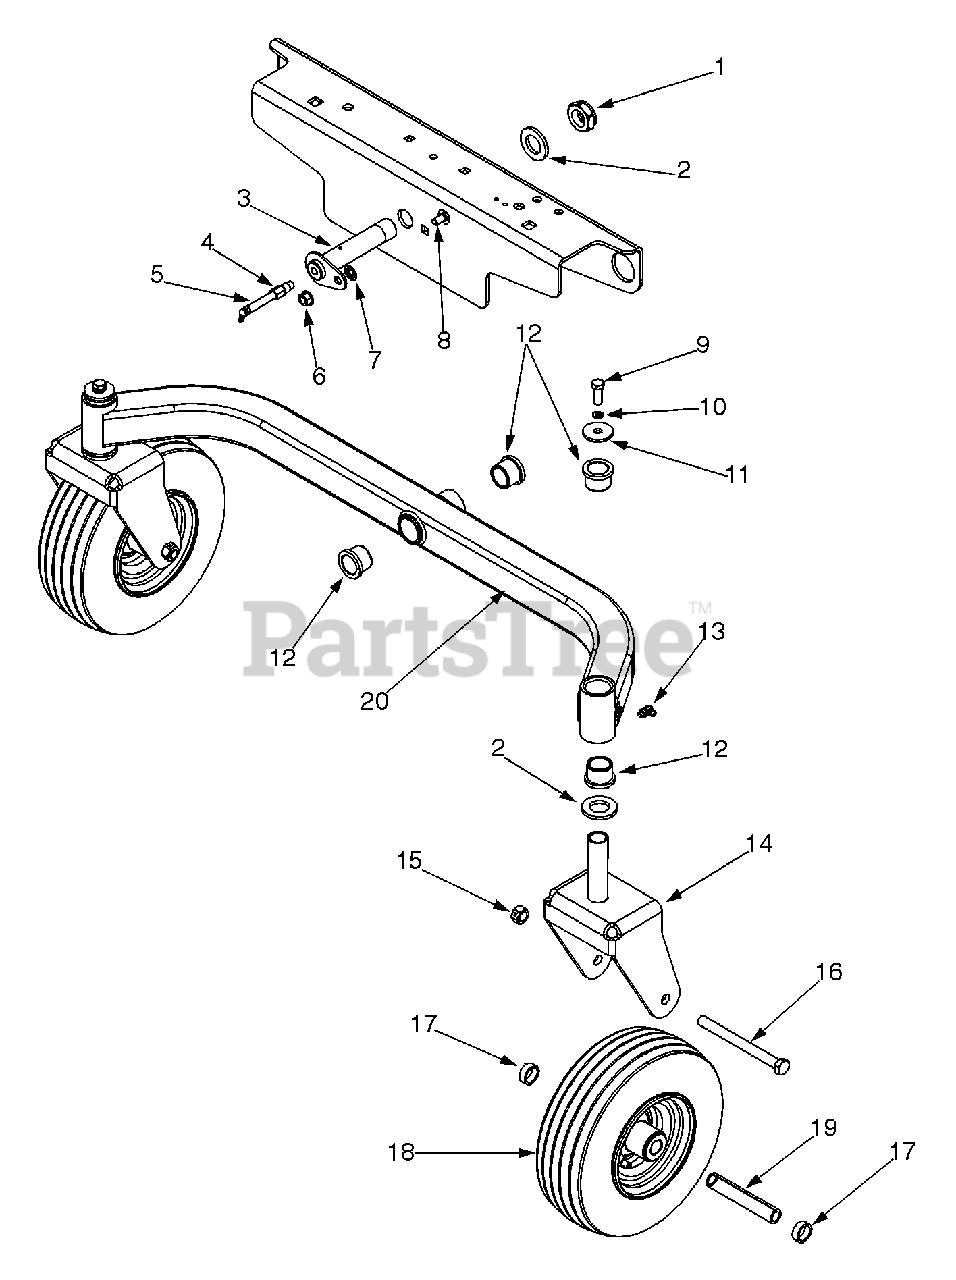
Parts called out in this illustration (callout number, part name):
1	Hex Lock Nut, 1.0-14
2	Flat Washer
3	Pin Ass'y, Pivot
4	Adapter, 1/8 NPTF x 1/8 NPTF
5	Grease Fitting, 65° w/Extension
6	Hex Flange Lock Nut, 3/8-16
7	Push Nut, 3/8 ID
8	Carriage Bolt, 3/8-16 x .75
9	Hex Cap Screw, 3/8-16 x 1.0
10	Lock Washer 3/8
11	Flat Washer 3/8 x 1.5
12	Flange Bearing 1.0 ID
13	Grease Fitting
15	Hex Center Lock Nut 1/2-20
16	Hex Cap Screw, 1/2-20 x 5.5
17	Spacer, .79 ID x .347 Lg
18	Wheel Comp 11.0 x 4.0 x 5.0
19	Wheel Spacer
